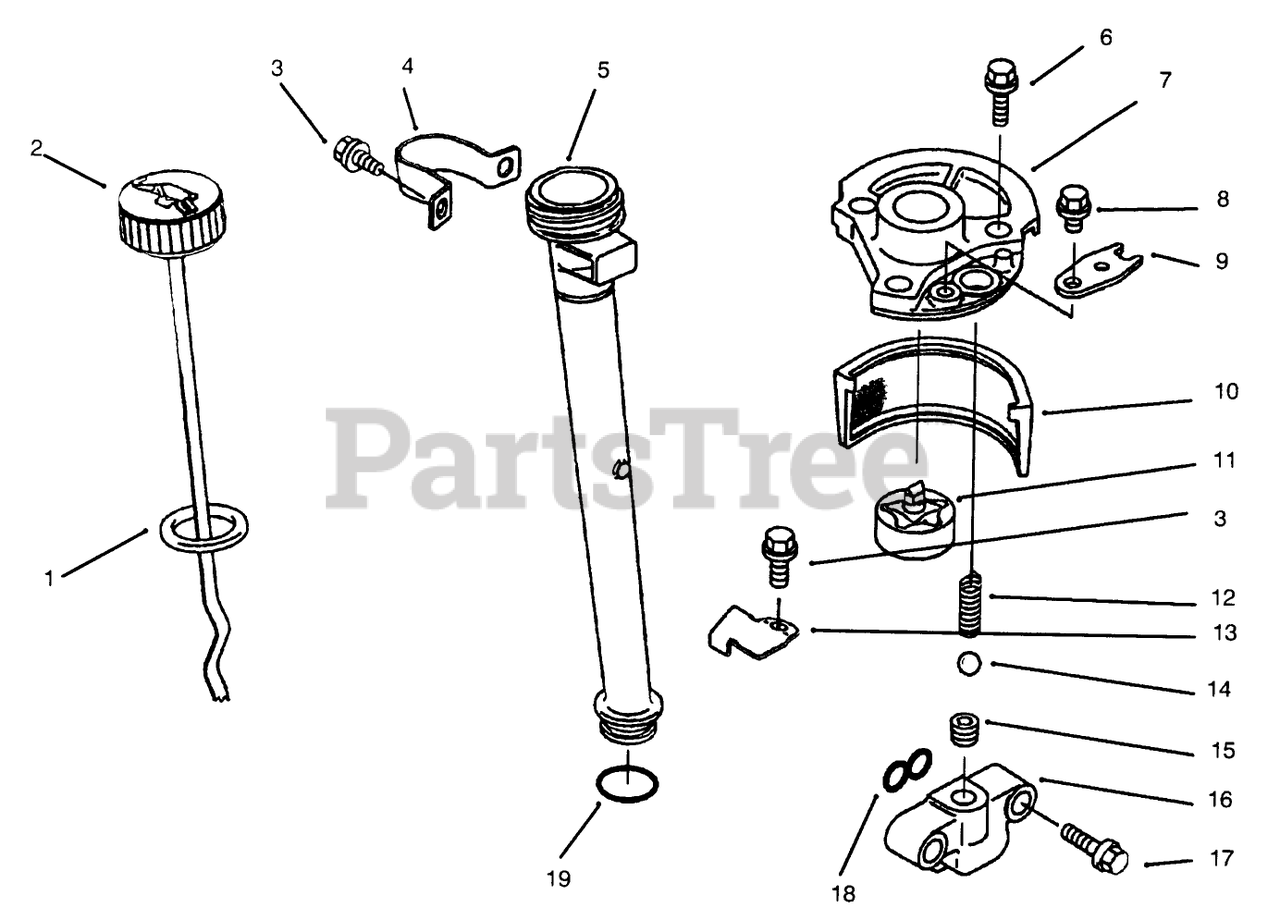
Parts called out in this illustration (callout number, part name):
1	Gasket
2	Gauge
3	Bolt
4	Clamp
5	Filler
6	Bolt-Flanged (8X25)
7	Cover-Pump
8	BOLT-FLANGED (6X10)
9	Plate
10	Filter-Oil
11	Pump ASM-Oil
12	Spring
13	Plate
14	Ball
15	Plug
16	Cover
17	Bolt
18	Seal
19	O-RING (16mm)
